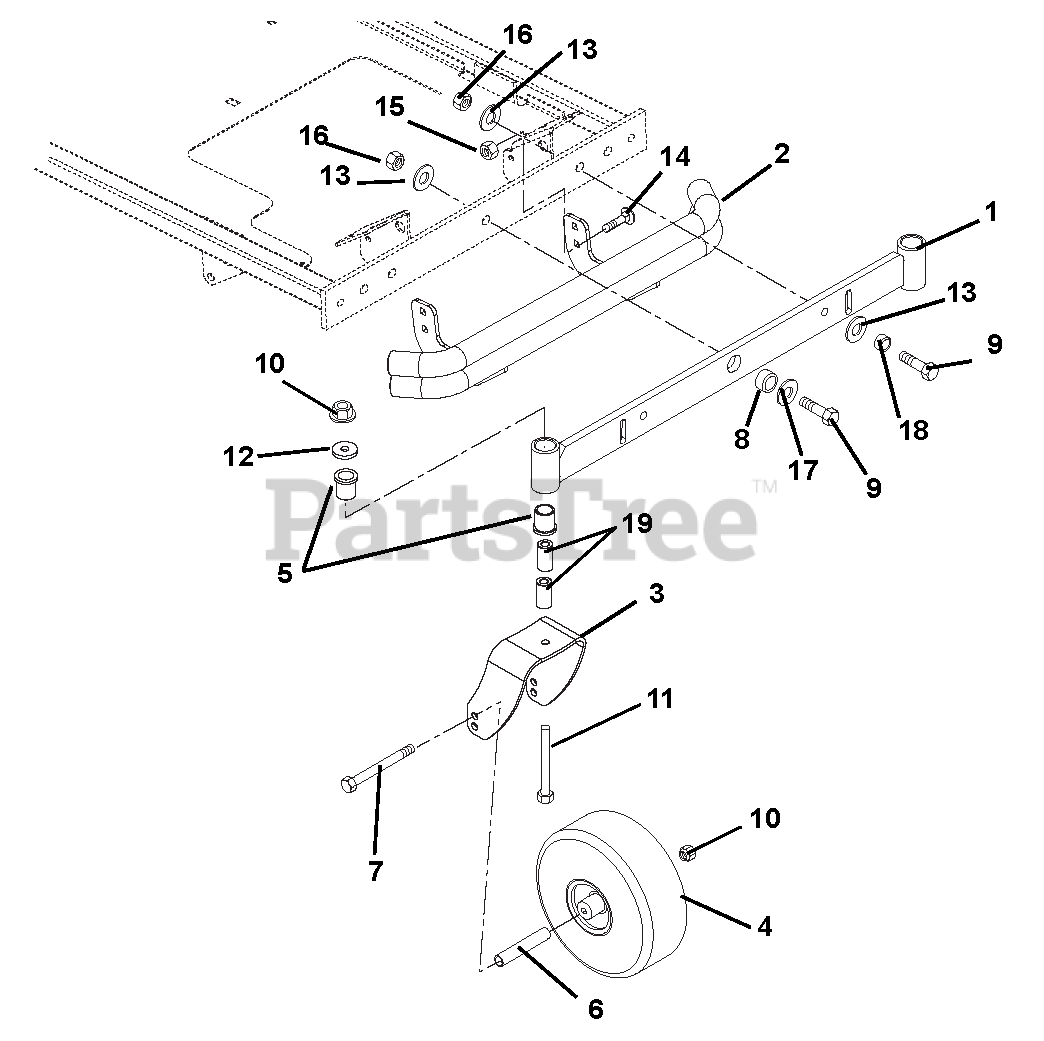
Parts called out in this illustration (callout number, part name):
1	WMT, FRONT AXLE
2	WMT, BUMPER
3	FORK, CASTER- WELDED
4	ASSY-TIRE 4 X 11 - 4 PLY
5	BSHG-FLG 1.00X1.25X1.50X1.50EP
6	SPACER, ROLLED WHEEL
7	@BLT-HEX .50-13X6.50 GR5 YWZC
8	BUSHING, AXLE PIVOT
9	BLT-HEX .62-11X2.25 YWZC GR8
10	@NUT-LK-TOP-FLG .50-13 YWZC
11	@BLT-HEX .50-13X5.00 GR5 YWZC
12	WSHR-FL-STL.511X1.441X.125 YWZ
13	WSHR-FLT .640X1.75X.250 YWZC
14	@BLT-RDHDSQNK .38-16X1.00 G5YZ
15	@NUT-LK-NYL-FLG .38-16 YWZC
16	@NUT-LK-NYL .625-11 YWZC
17	@WSHR-FL-STL.688X1.75X.134 YWZ
18	SPACER, .750 D X .558 LONG
19	SPACER, CASTER .50X1.00X1.84
